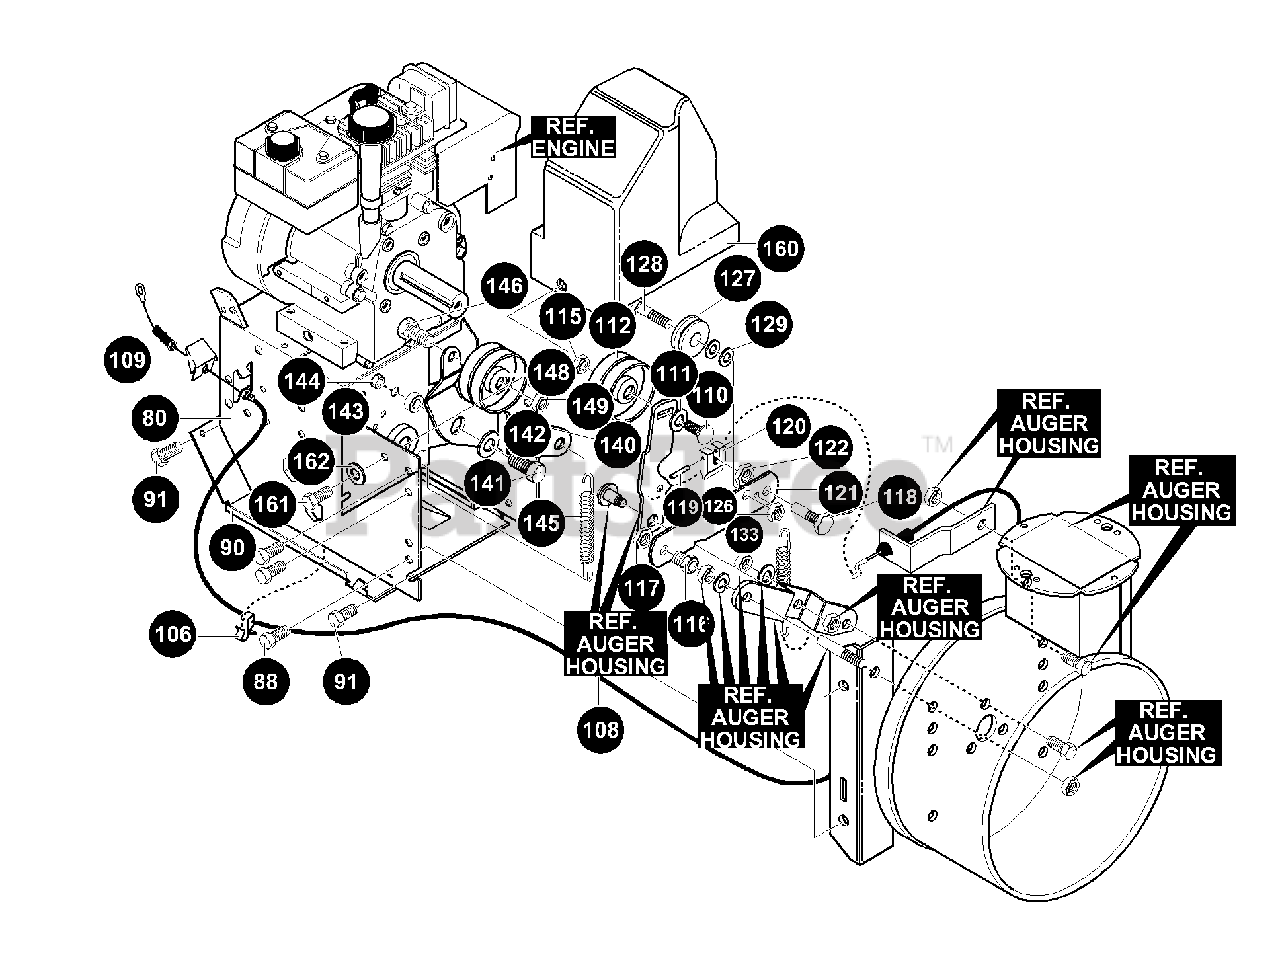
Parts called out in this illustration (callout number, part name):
80	FRAME, ASSY
88	SCREW, 5/16-18X .50
90	COVER, BOTTOM
91	SCREW, 1/4-20X .63
100	PLATE, CLUTCH
106	CLIP, CABLE TINN
108	CABLE, AUGER
109	SHIELD, CABLE GUARD
110	C. BOLT, 3/8-16X1.25
111	FLATWASHER
112	PULLEY, IDLER
115	NUT, 3/8-16
116	BOLT, BRAKE ARM
117	NUT, 9/16-18 JAM
118	BOLT, BRAKE ARM
119	SPRING PIN
120	PAD, AUGER/IMP
121	BRACKET, PUCK
122	NUT, 1/4-20 RGHEXCTRLK
126	NUT, 1/4-20
127	PULLEY, METAL
128	SH BOLT 1/4-20
129	FLATWASHER
133	SPRING, IDLER
140	LEVER, IDLER ARM TRACTION
141	SCREW, 5/16-18X .75
142	FLATWASHER, .328X1.25X.075
143	BUSHING, IDLER LEVER
144	NUT, 5/16-18 HEXNYL
145	IDLER SPRING
146	SCREW, 3/8-16X1.25
148	PULLEY, IDLER
149	NUT, 3/8-16
160	COVER, BELT
161	SCREW, 1/4-20X .63
